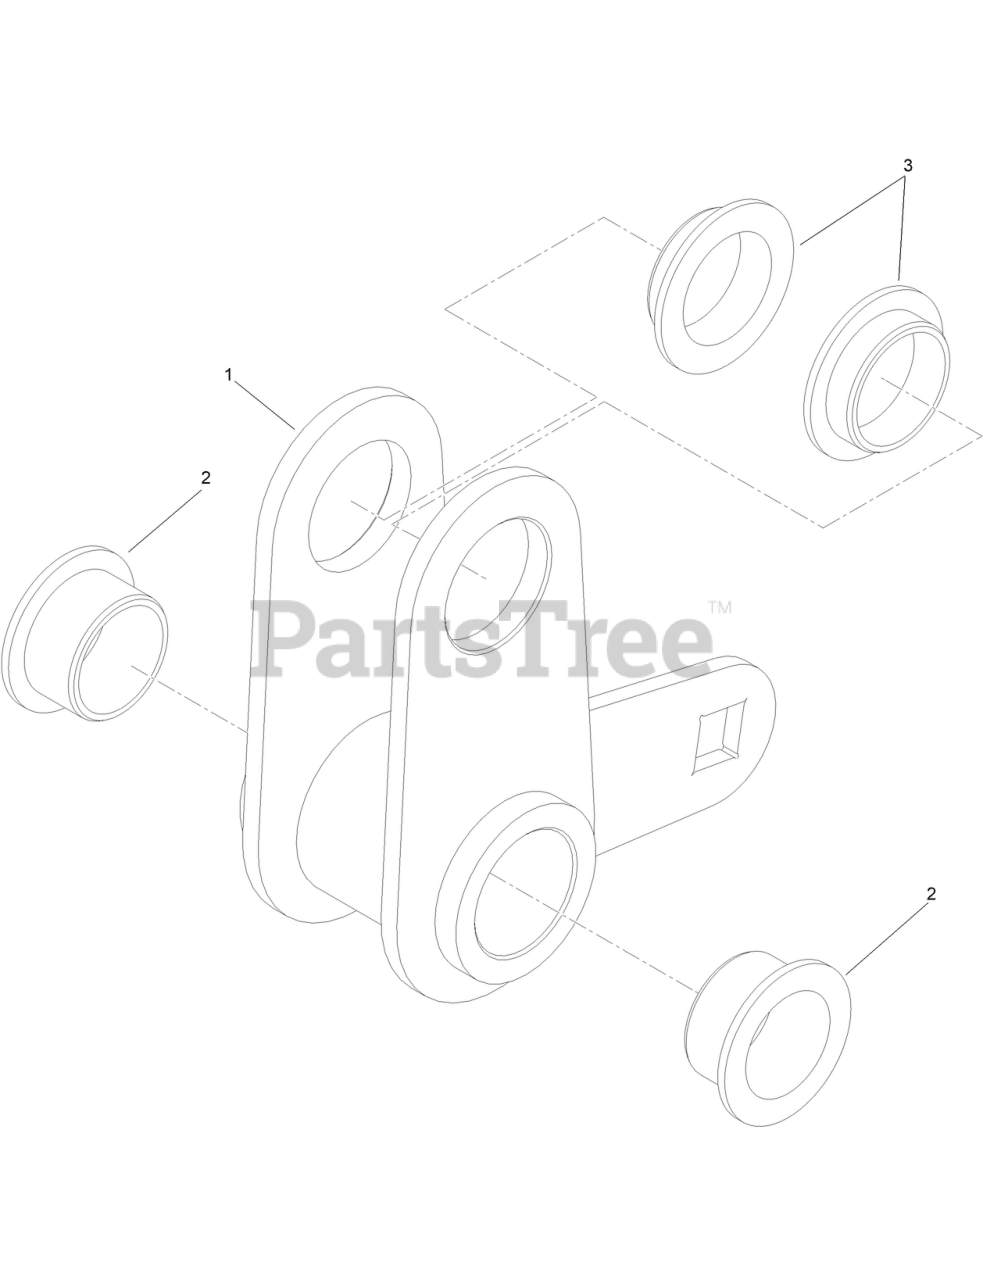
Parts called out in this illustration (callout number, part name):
1	BELLCRANK-BRAKE
2	BUSHING-FLANGE
3	BUSHING-FLANGE
